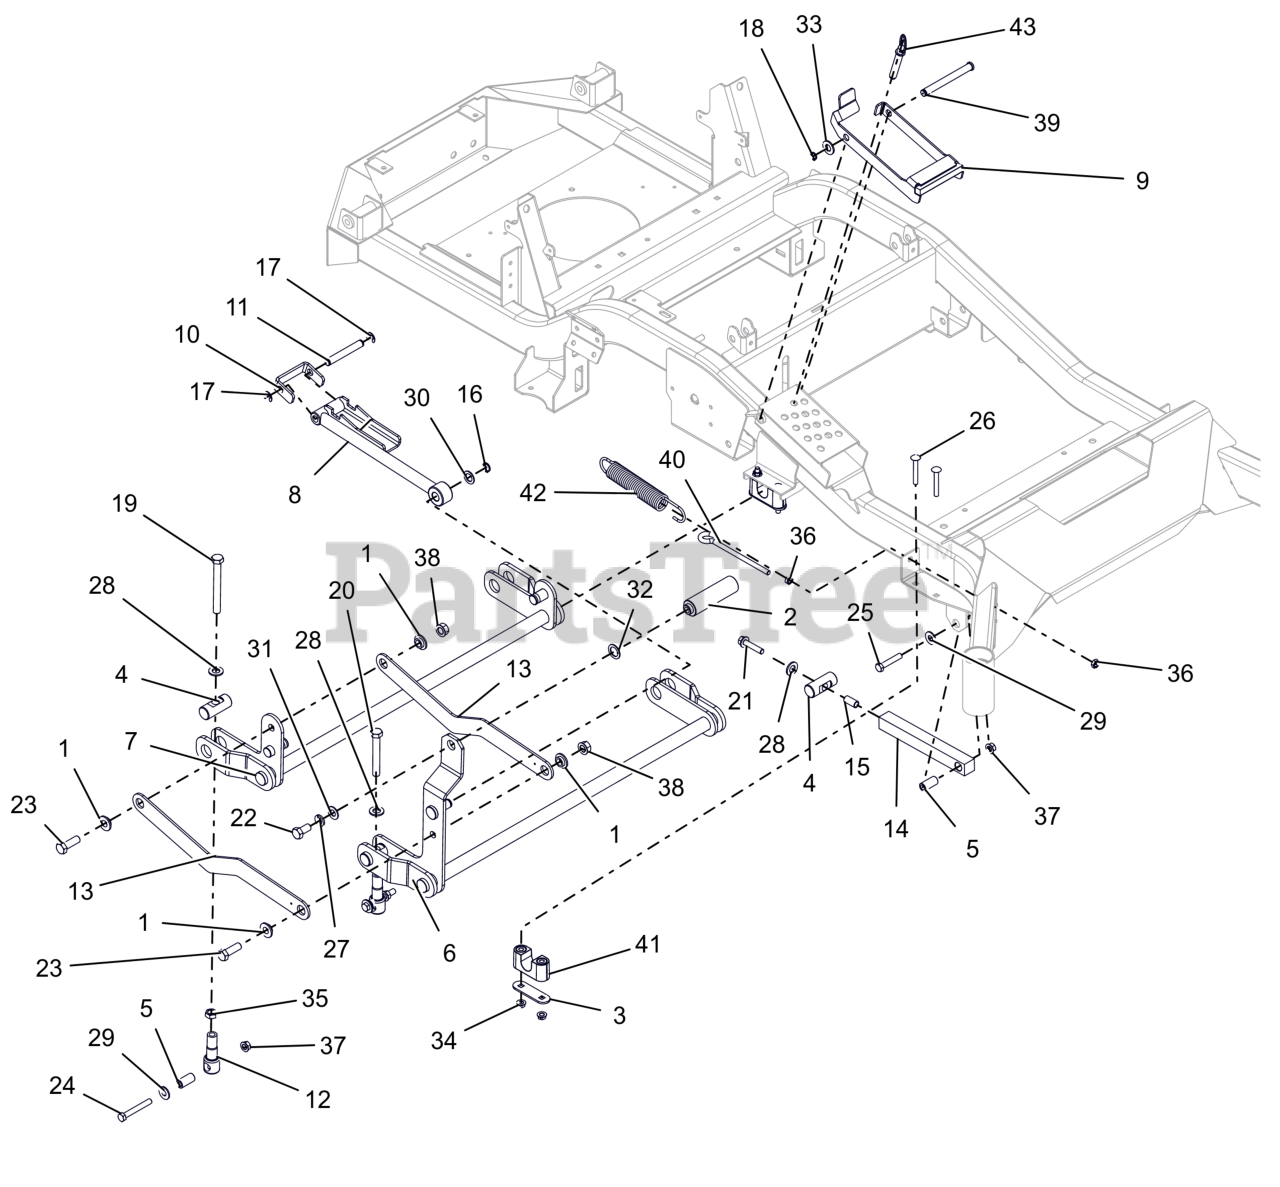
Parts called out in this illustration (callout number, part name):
1	BSHG-FLG .515X.750X.395X1.120
2	FOOT PEG, DECK LIFT
3	PLATE, BEARING SUPPORT
4	PIN, DECK LIFT
5	SPACER, DECK LEVELING
6	WLDMT, FRONT DECK LIFT PIVOT
7	WLDMT, REAR DECK LIFT PIVOT
8	WLDMT, HOC ARM
9	BRKT, HOC TRANSFER LOCK
10	BRKT, HOC LINE
11	ROD, HOC PIVOT
12	LINK, DECK LIFT FORMED
13	LINK, DECK LIFT
14	LINK, DRAG
15	BSHG-SLV .385X.500X1.045
16	RG-RTNG-EXT .625X.050
17	RG-RTNG-EXT .500X.042 (E)
18	RG-RTNG-EXT .500X.050 (SNAP)
19	@BLT-HEX .5-13-4.5GR8 FULL THD
20	BLT-HEX .50-13X3.50 GR5 FTH
21	BLT,HEX-FLG .38-16X1.75 G5 ZCC
22	@BLT-HEX .50-13X1.00 GR5 YWZC
23	@BLT-HEX .50-13X1.50 GR5 YWZC
24	BLT-HEX .38-16X2.75 GR8 YWZC
25	@BLT-HEX .38-16X2.00 GR5 YWZC
26	BLT-RDHDSQSHNK .31-18X2.25 YWZ
27	@WSHR-LK .50X.125 REG YWZC
28	FLATWASHER 1/2 SAE HARD 15906
29	@WSHR-FL-STL.438X1.00X.083 YWZ
30	WSHR-FL-STL .630X1.005X.062 YZ
31	WSHR-FL-STL .505X1.00X.062YWZC
32	WSHR-FL-STL.754X1.125X.062YWZC
33	@WSHR-FL-STL.531X1.06X.095YWZC
34	@NUT-LK-CTR-FLG .31-18 YZ GR F
35	NUT-JAM .50-13 YWZC
36	NUT-HEX-JAM .375-16 YWZC
37	@NUT-LK-TOP-FLG .38-16 YWZC
38	@NUT-LK-TOP-FLG .50-13 YWZC
39	PIN-CLEV .50X4.75X4.55
40	BOLT,.38-16 X 5.25-.62 DIA EYE
41	ASM-BUSHING, DECK LIFT
42	SG-TENS .162X1.25X8.25 WLD 25
43	PIN, .50 X 2.20 USABLE LG BALL
